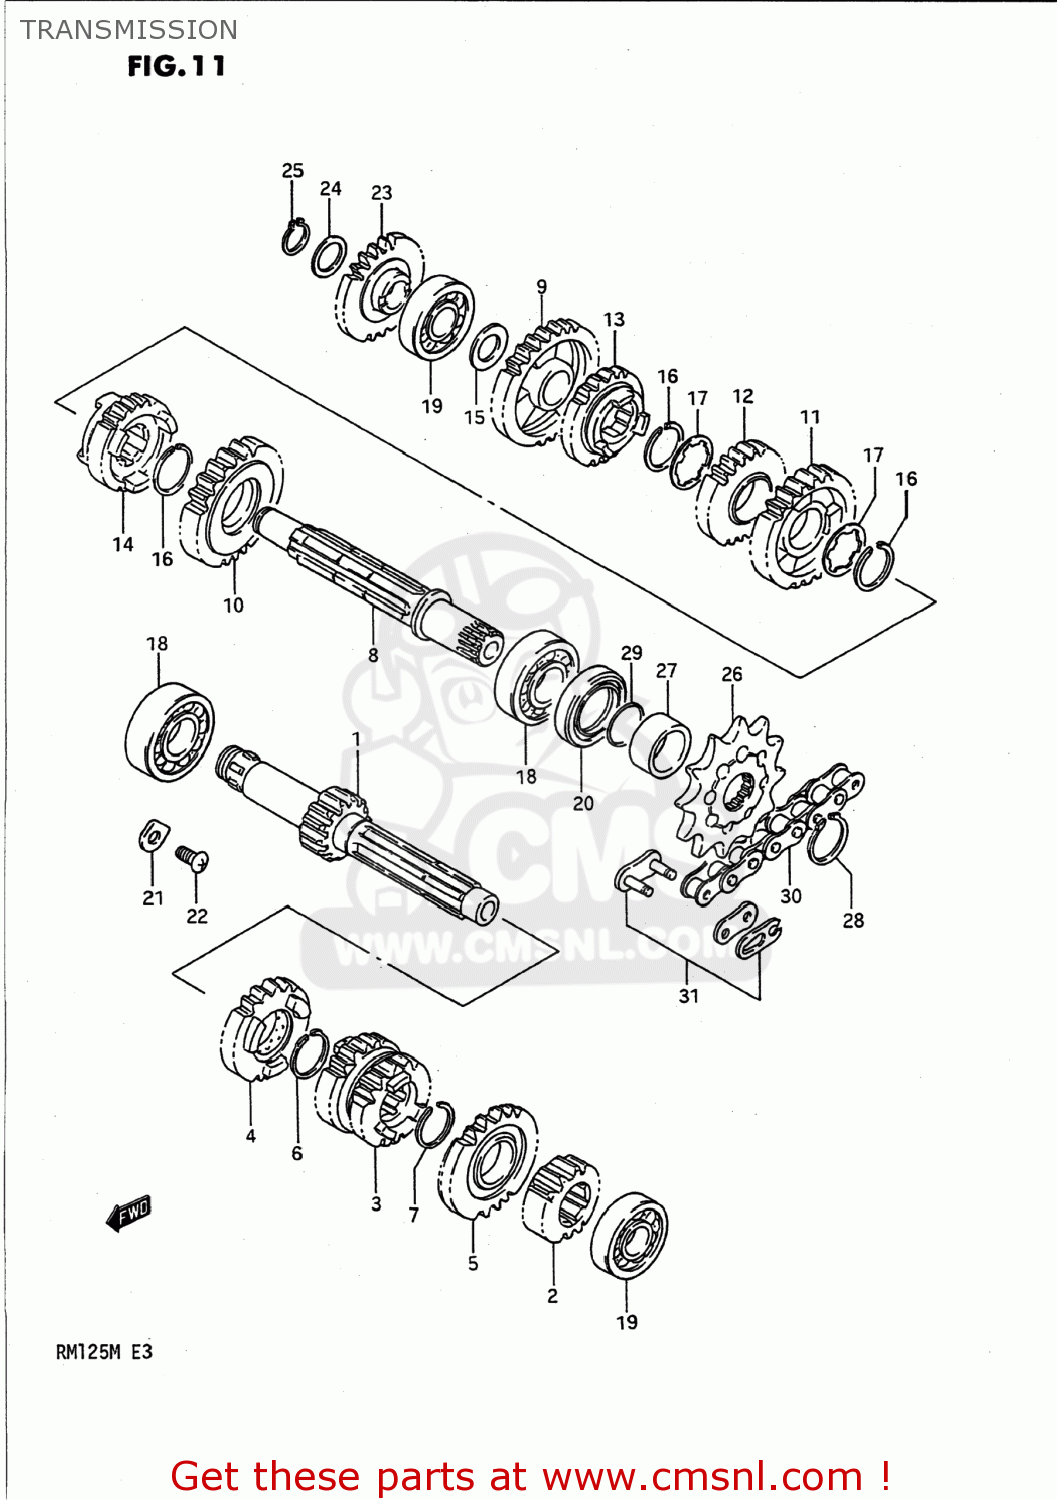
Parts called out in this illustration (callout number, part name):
1	SHAFT,COUNTER
2	GEAR,SECOND DRIVE (NT:16)
3	GEAR,THIRD & FOURTH DRIVE
4	GEAR,FIFTH DRIVE (NT:19)
5	GEAR,SIXTH DRIVE (NT:20)
6	CIRCLIP
7	CIRCLIP
8	SHAFT,DRIVE
9	GEAR,1ST DRIVEN
10	GEAR,SECOND DRIVEN (NT:28)
11	GEAR,THIRD DRIVEN (NT:23)
12	GEAR,FOURTH DRIVEN (NT:24)
13	GEAR,FIFTH DRIVEN (NT:20)
14	GEAR,SIXTH DRIVEN (NT:19)
15	WASHER,THRUST
16	CIRCLIP
17	WASHER,LOCK
18	BEARING
19	BEARING
20	SEAL,OIL(25X40X7)
21	RETAINER,SHIFT CAM,R BEARING
22	SCREW 6X12
23	GEAR,KICK STARTER IDLE
24	WASHER,THRUST
25	CIRCLIP,15MM
26	SPROCKET,ENGINE
27	SPACER(20X25X12.8)
28	CIRCLIP
29	O RING(D:1,ID:19.5)
30	CHAIN ASSEMBLY,DRIVE
31	JOINT ASSEMBLY,CHAIN
